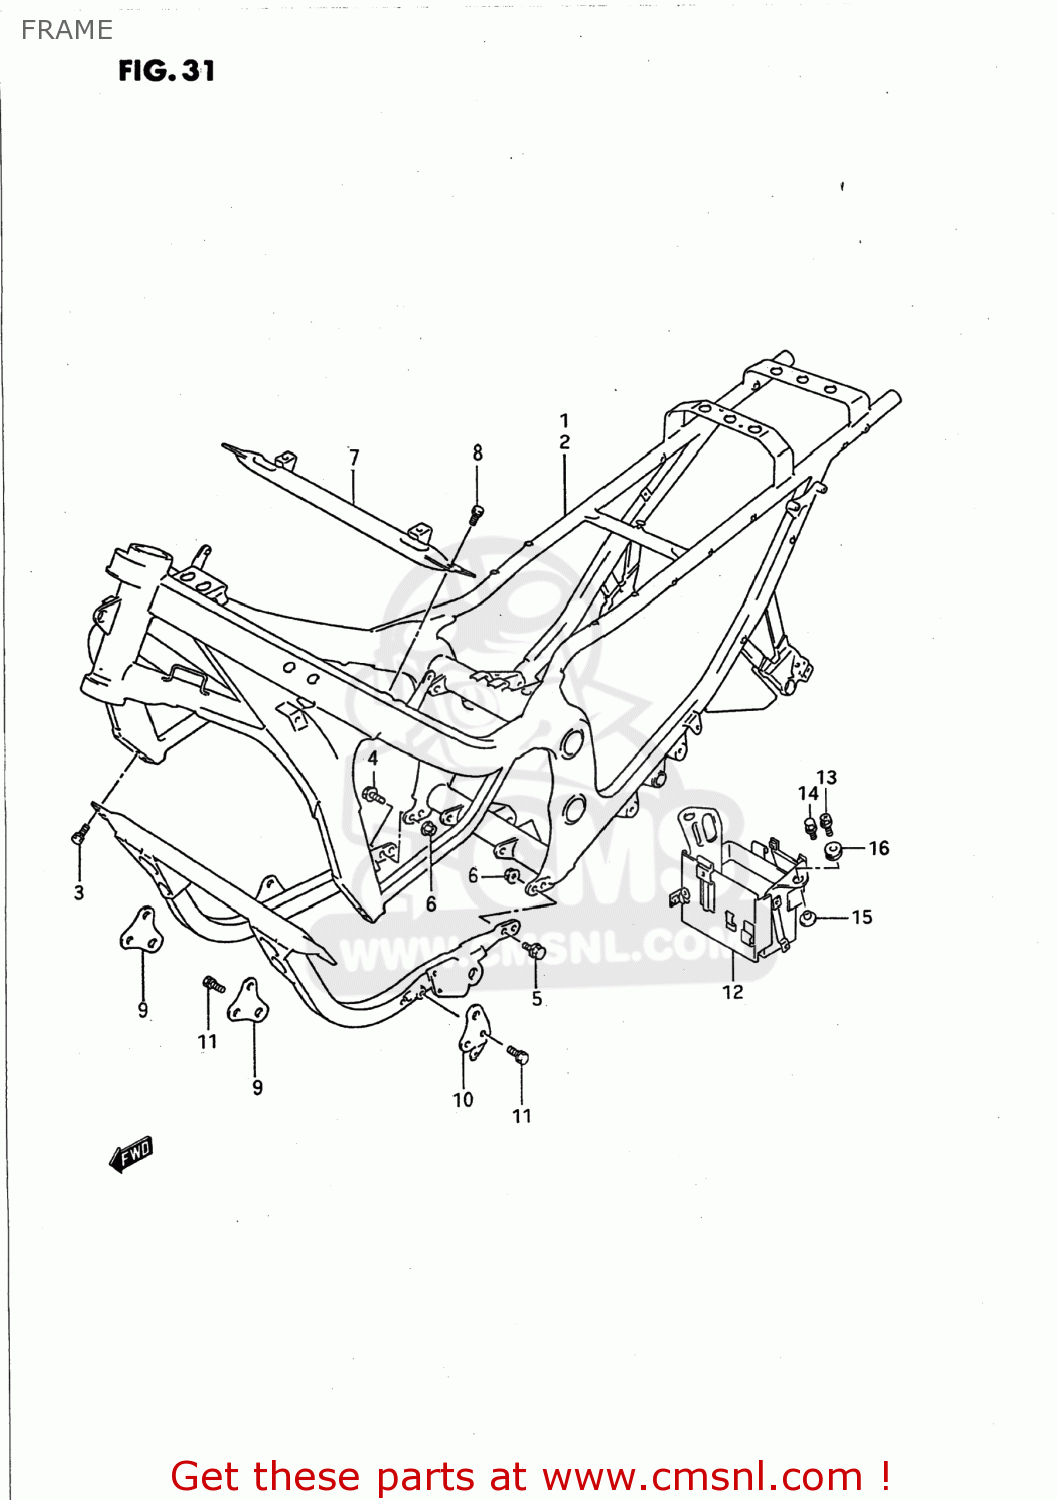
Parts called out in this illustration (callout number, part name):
1	FRAME
2	FRAME SET
3	BOLT
4	BOLT
5	BOLT
6	NUT
7	TUBE,FRAME
8	BOLT
9	PLATE,ENG MTG NO.1
10	PLATE,ENG MTG NO.2,L
11	BOLT
12	HOLDER,BATTERY
13	BOLT L:30
14	BOLT
15	SPACER COMP,BATTERY
16	CUSHION
